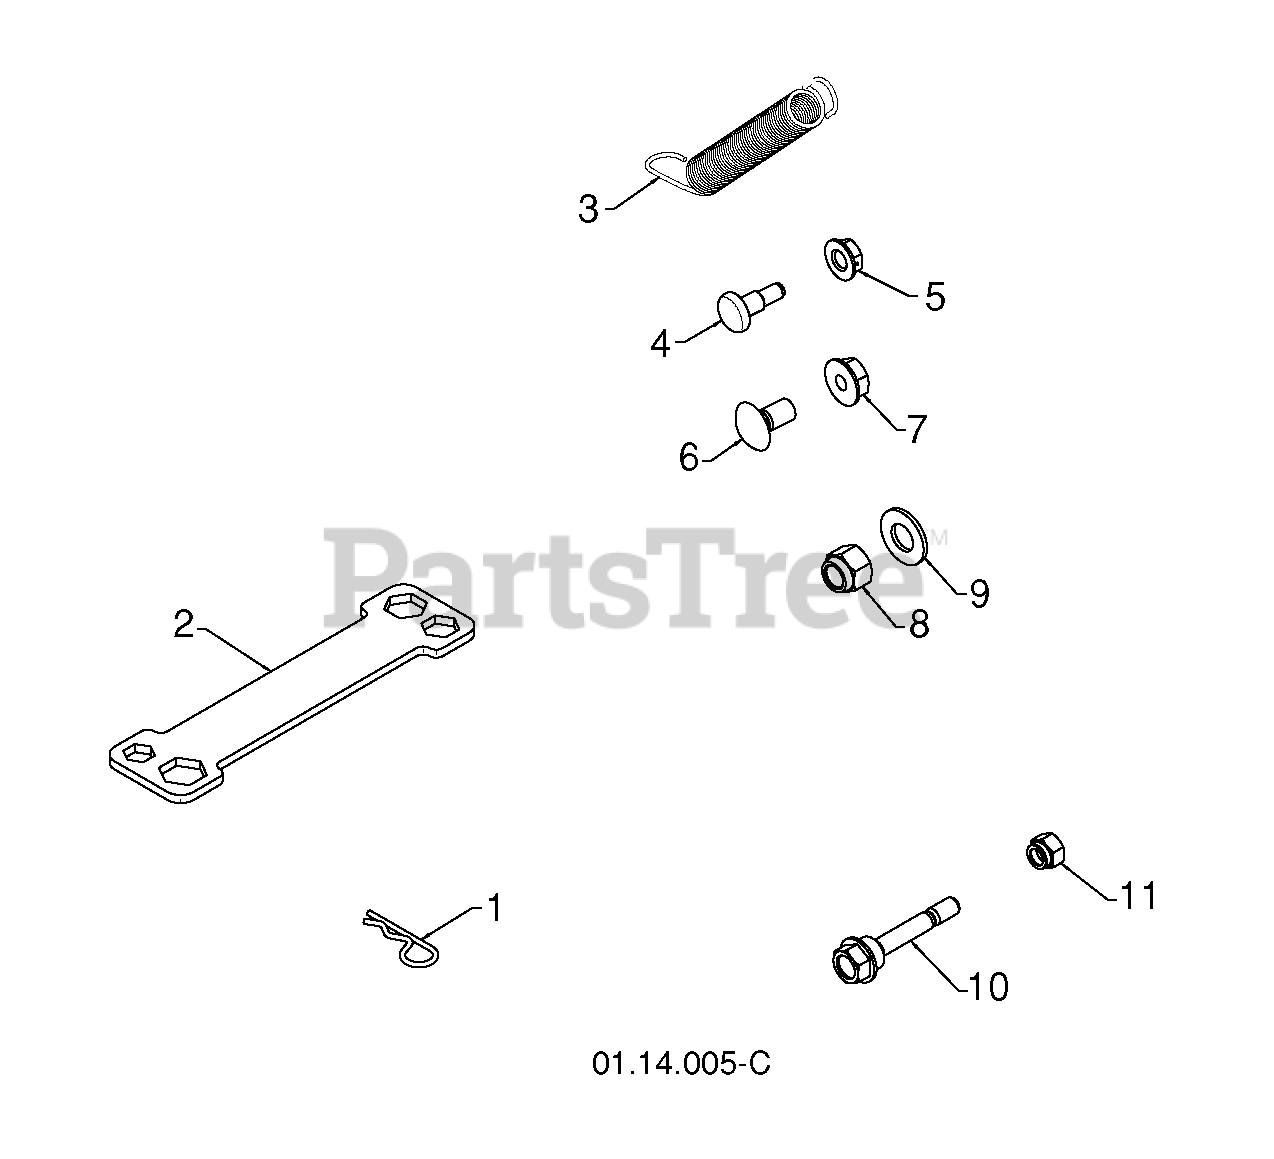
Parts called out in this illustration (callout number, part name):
1	SPRING RETAINER
2	WRENCH.SNOWTHROWER
4	BOLT, SHOULDER
5	NUT.HEX.FLANGE.1/4
6	BOLT
7	NUT, LOCK 5/16-18
8	NUT
10	BOLT, SHOULDER SHEAR
11	LOCKNUT
